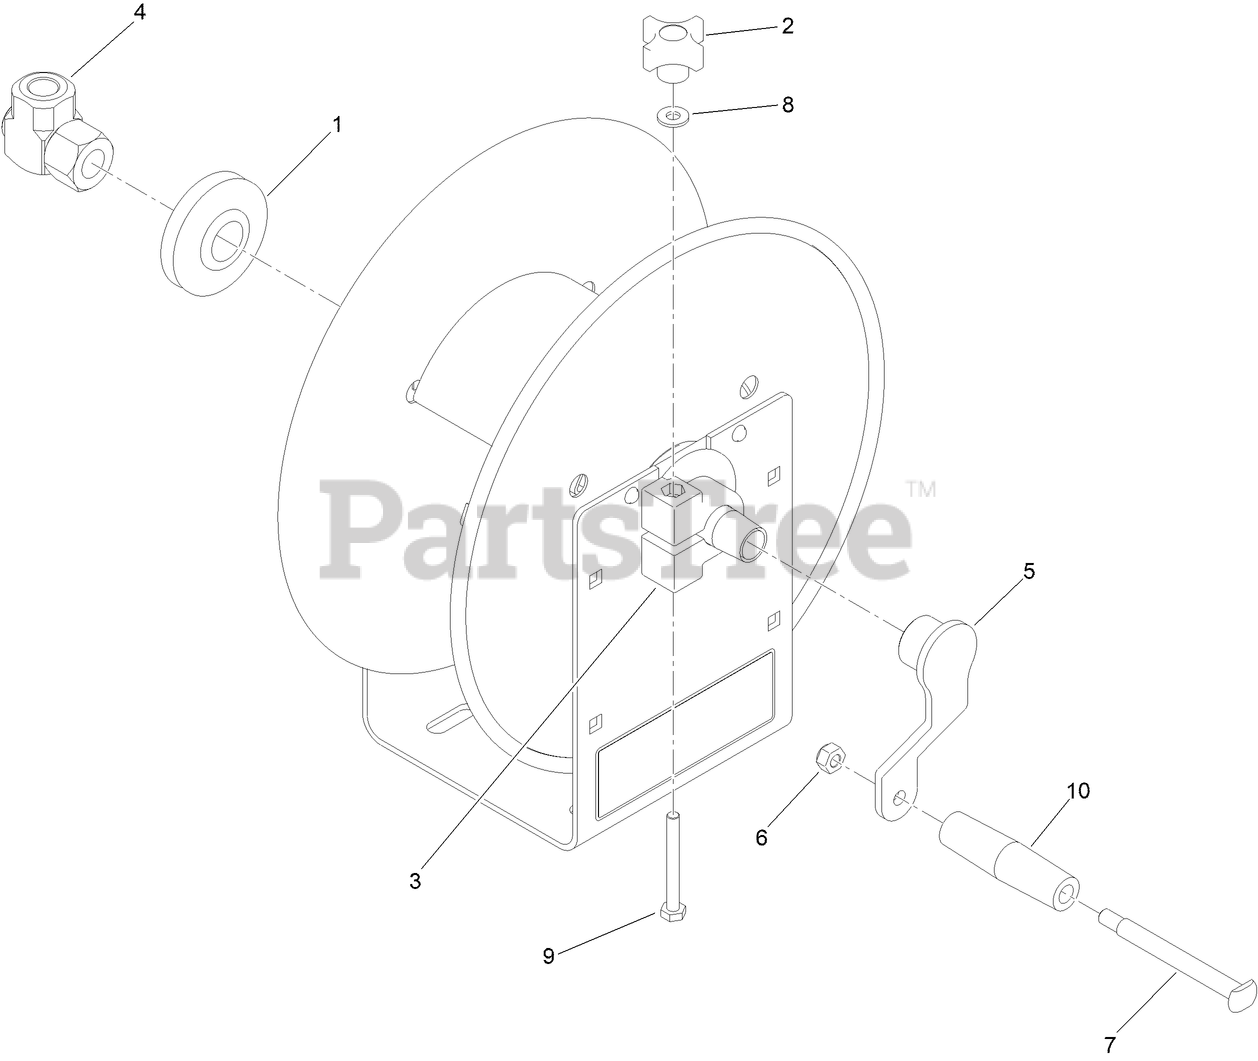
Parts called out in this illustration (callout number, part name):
1	PLASTIC BEARING
2	HOSE REEL BRAKE KNOB
3	BRAKE/BEARING 6329-1-1
4	SWIVEL 3/8" NPT
5	Crank-Reel
6	NUT-HEX
7	BOLT, HOSE REEL HANDLE
8	Washer-Flat
9	SCREW-HH
10	HANDLE ,HOSE REEL
